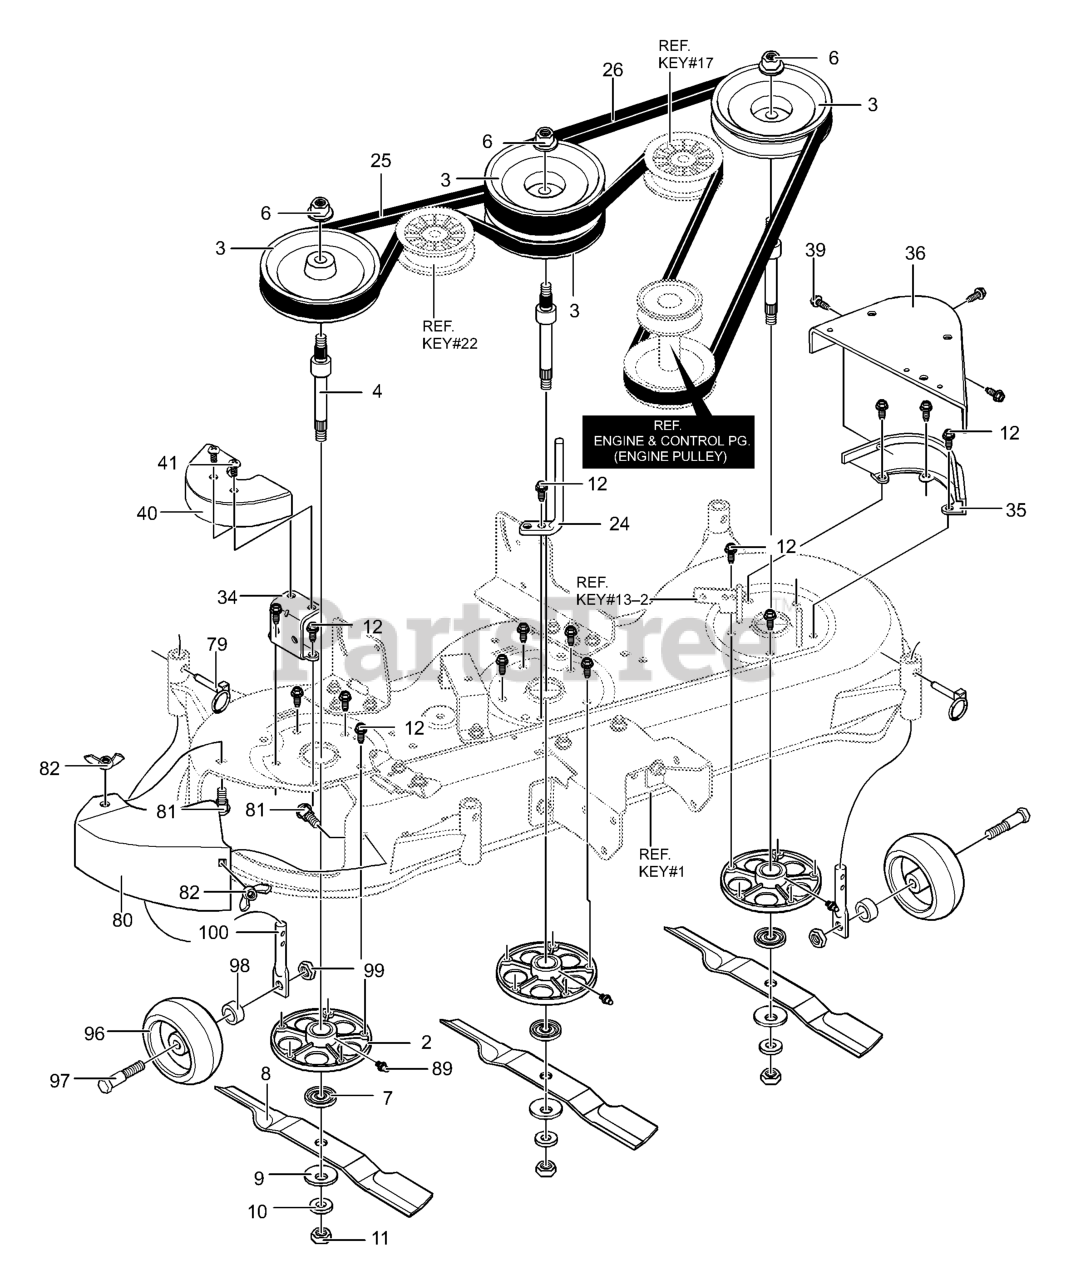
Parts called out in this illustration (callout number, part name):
2	HOUSING, JACKSHAFT
4	JACKSHAFT
6	NUT, 9/16-18
7	HUB, BLADE ADAPTER
8	BLADE, MULCHING
12	BOLT-3/8 X 1.25
24	ROD, BELT GUIDE
25	BELT, Arbor Drive (37X66) 46" Mower Deck
26	BELT, Drive (37X89) 46" Mower Deck
34	BRACKET, PULLEY COVER
35	BRACKET, PULLEY COVER
36	COVER, LEFT PULLEY
39	SCREW, 5/16-18 x 0.50
40	COVER, RIGHT PULLEY
79	PIN, LYNCH
80	PLATE, BLOCK OFF MULCH
81	BOLT, 5/16-18X .75
82	NUT, WING 5/16-18
89	ZERK, GREASE
96	WHEEL, GAUGE
99	NUT, JAM
100	ROD, GAUGE
